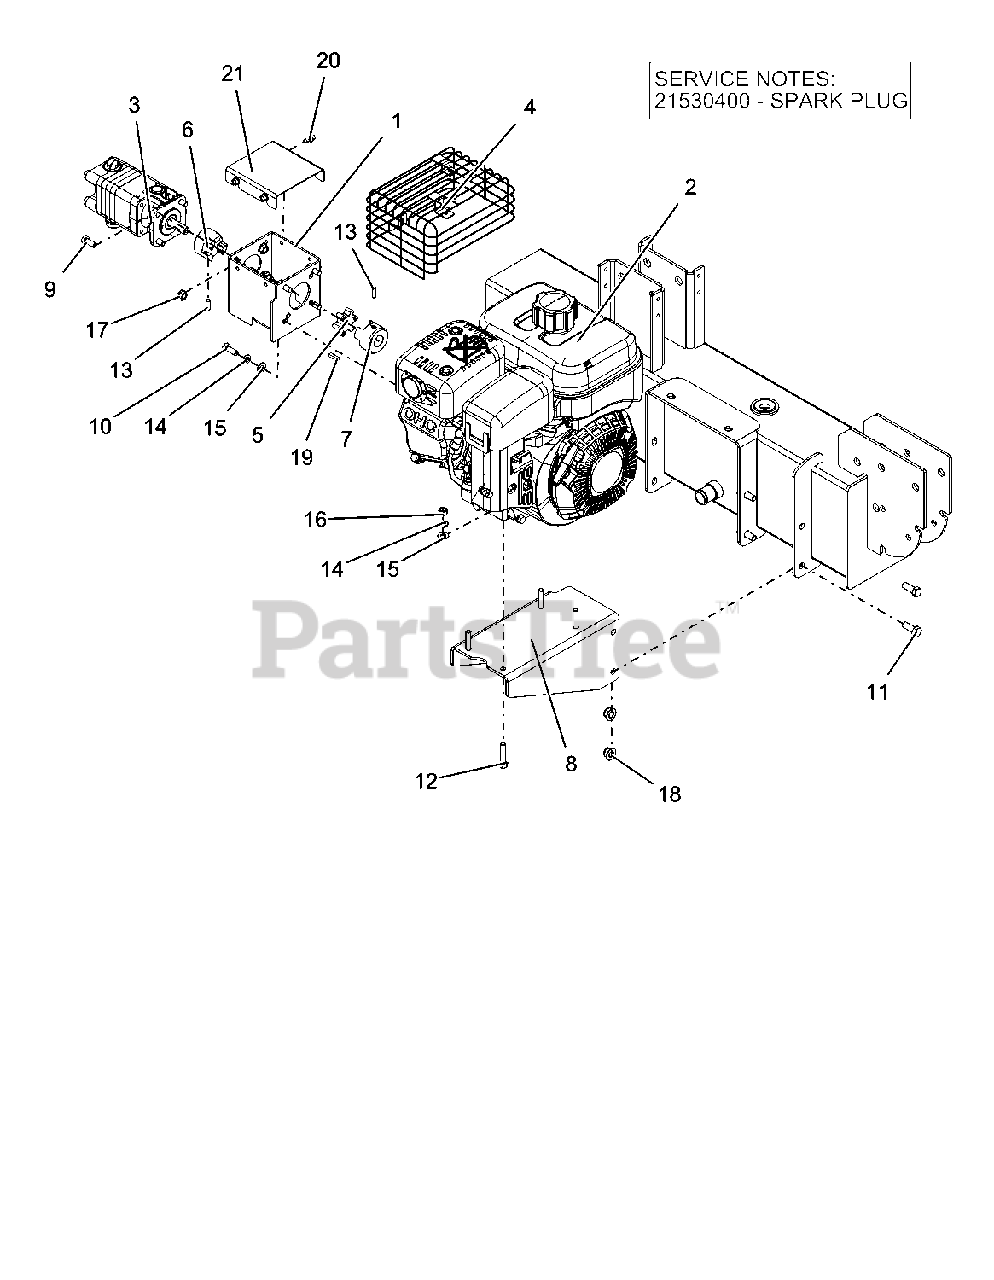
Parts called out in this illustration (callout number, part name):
1	WLDMT, PUMP MOUNT
2	ENGINE, SUBARU 6HP SP170 (CARB)
3	PUMP, SPLITTER - 11 GPM
4	GUARD, MUFFLER - SUBARU
5	COUPLER, CONNECTOR SPIDER
6	COUPLER, DRIVE 1/2"
7	COUPLER, DRIVE 3/4"
8	MOUNT, ENGINE (ORANGE)
9	BLT-HEX .31-18X.75 GR5 YWZC
10	BLT-HEX .31-24X.75 GR5 YWZC
11	BLT-HEX .38-16X1.00 GR5 YWZC
12	BLT-HEX .31-18X1.50 GR5 YWZC
13	SCR-SET, 25-20X.75 SKHCUPDL REV
14	WSHR-LK .31X.097 HVY YWZC
15	WSHR-FL-STL.344X.688X.065YWZC
16	NUT-HEX .31-18 YWZC
17	NUT, LK-TOP-FLG .312-18 YWZC
18	NUT-LK-NYL-FLG .38-16 YWZC
19	KEY-SQ .188X.188X.750
20	SCR-TAP .25-20X.50 HWH TR YWZ
21	COVER, COUPLING
22	SPARK PLUG
